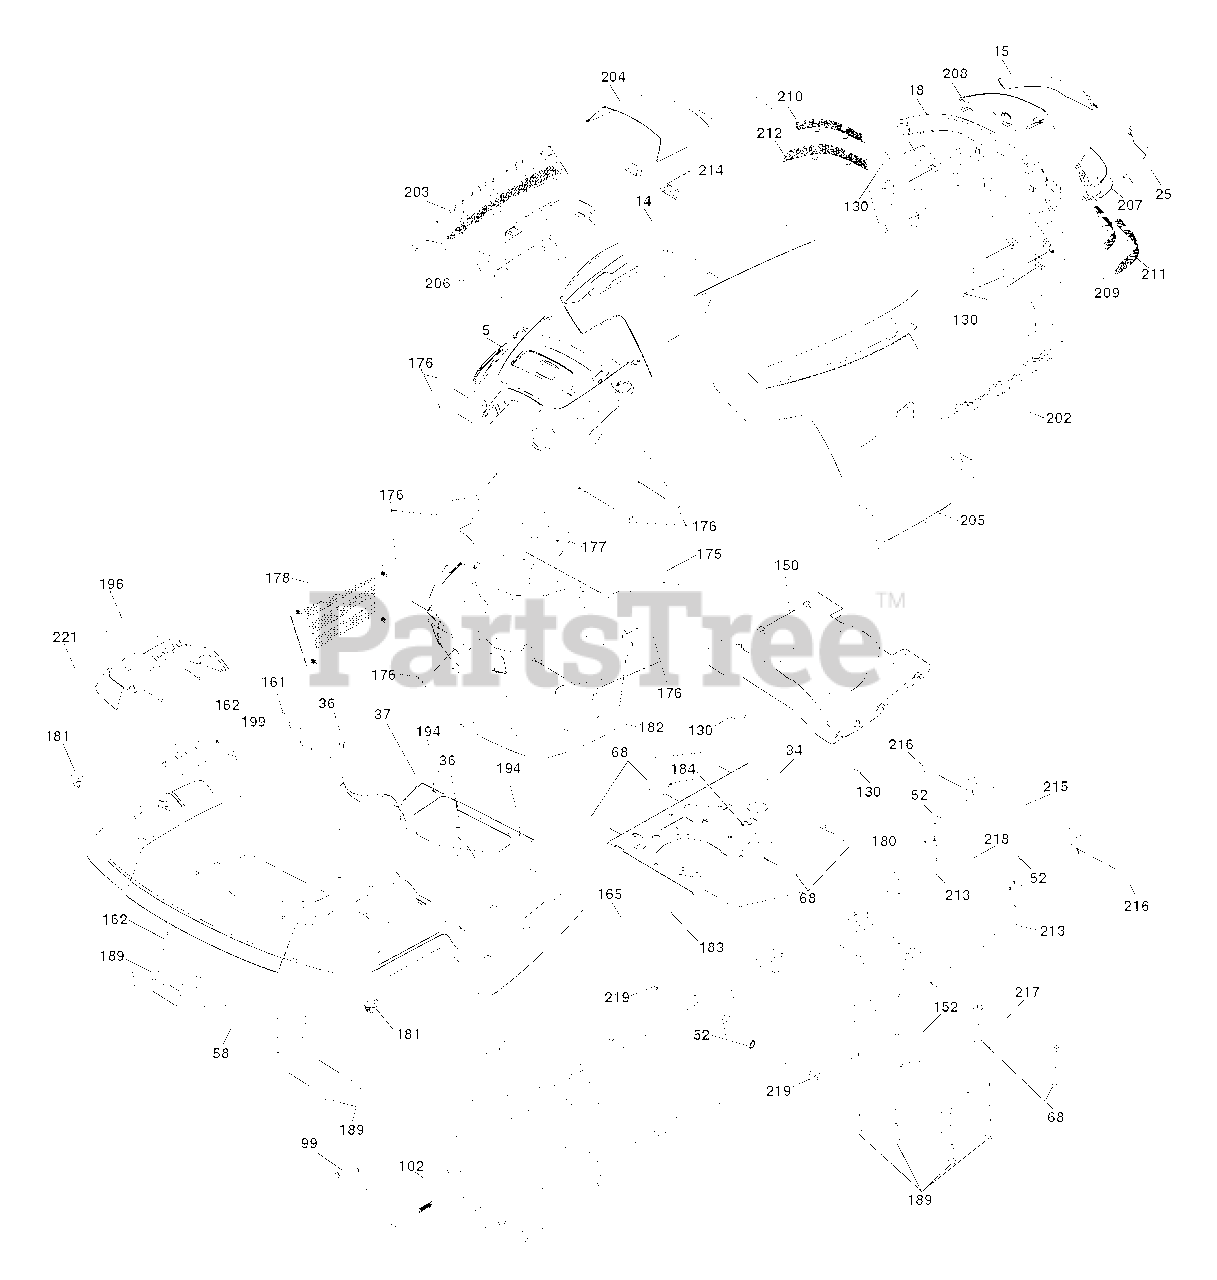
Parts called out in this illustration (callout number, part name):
5	Dash
14	Hood
18	Grille
34	Plate Engine
37	Fender
52	Nut 5/16-18
58	Bracket Fender
68	Screw 5/16-18 x 1/2
99	Rod Bypass
102	Retainer Spring
130	Screw 10 x 3/4 Single Lead Hex
139	Bolt Shoulder 5/16-18
150	Duct Heat Hood
152	Shield Browning/Debris
156	Screw 5/16-18 x 3/4
161	Console Fuel Window
162	Screw Hex Wsh Hi-Lo 1/4 x 1/2
165	Bracket Support Tank
175	Crossmember
176	Screw 10-24 x 5/8 Rnd Qdrx
177	Bushing Steering
178	Cargo Asm. Net
180	Chassis
181	Bushing Mtg. Fender Crgo.
182	Dash Lower
185	Bolt Carr. 5/16-18 x 1-1/4 Gr. 5
189	Screw 5/16-18 x 3/4
194	Nut Lock Hex Flange 5/16-18
196	Console Asm. Deck Lift
199	Plate Deck Lift
202	Vent Side Hood RH
203	Vent Side Hood LH
204	Vent Asm Hood Top
205	Skirt Hood Side RH
206	Skirt Hood Side LH
209	Insert Hex Top RH
210	Insert Hex Top LH
211	Insert Hex Bottom RH
212	Insert Hex Bottom LH
213	Bolt Hex Hd 5/16-18 unc x 3/4
214	Clip Retainer
215	Cover Chassis Front
216	Screw 5/16-18 x 1/2
217	Rod Pivot
219	Stud Fastner
221	Reflector LH
